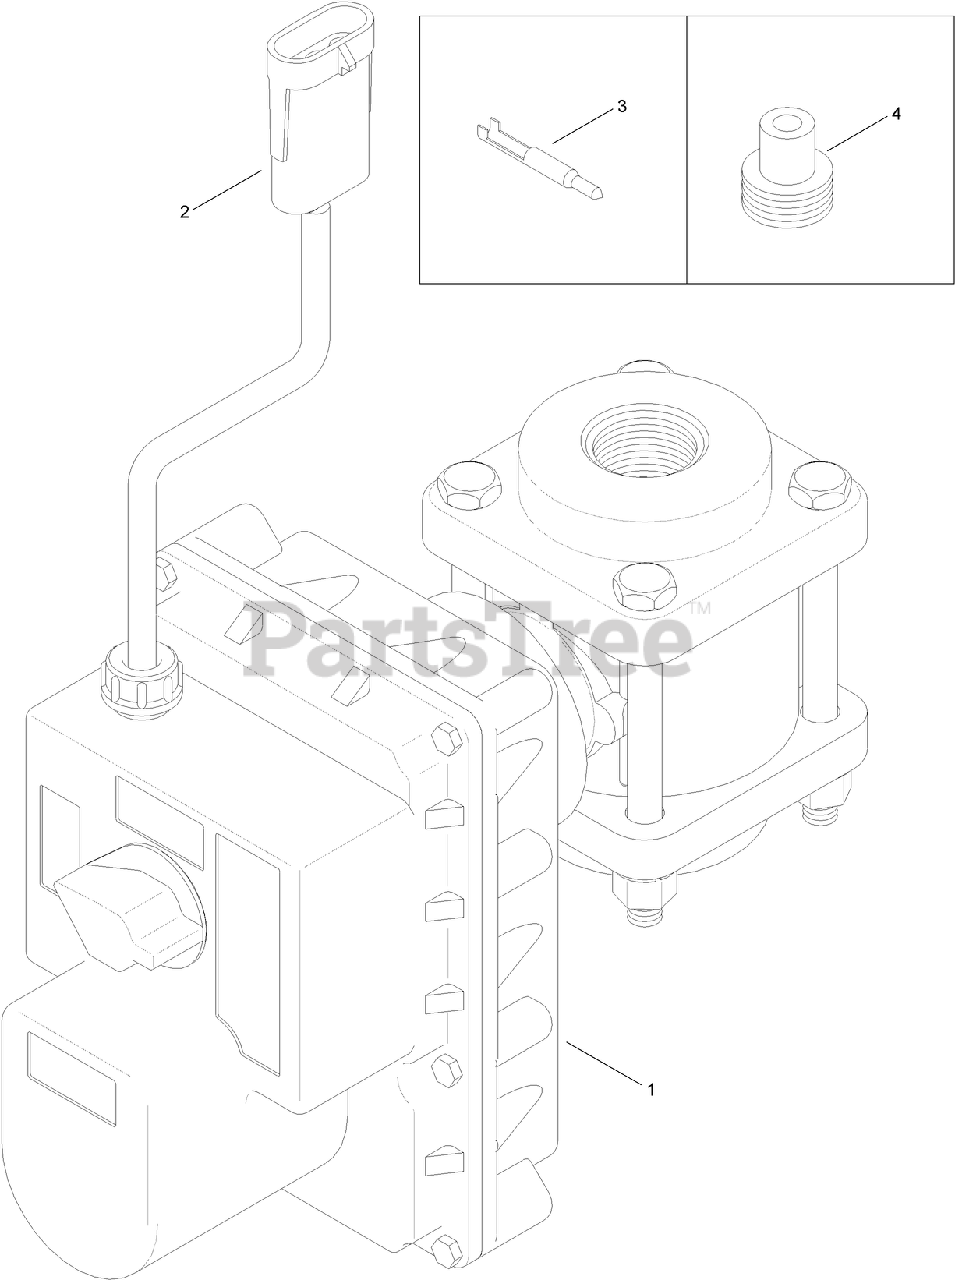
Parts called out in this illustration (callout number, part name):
1	WATER SHUTOFF VALVE ASM
2	CONNECTOR-MALE, 3-WAY (BODY ONLY)
3	TERMINAL-MALE
